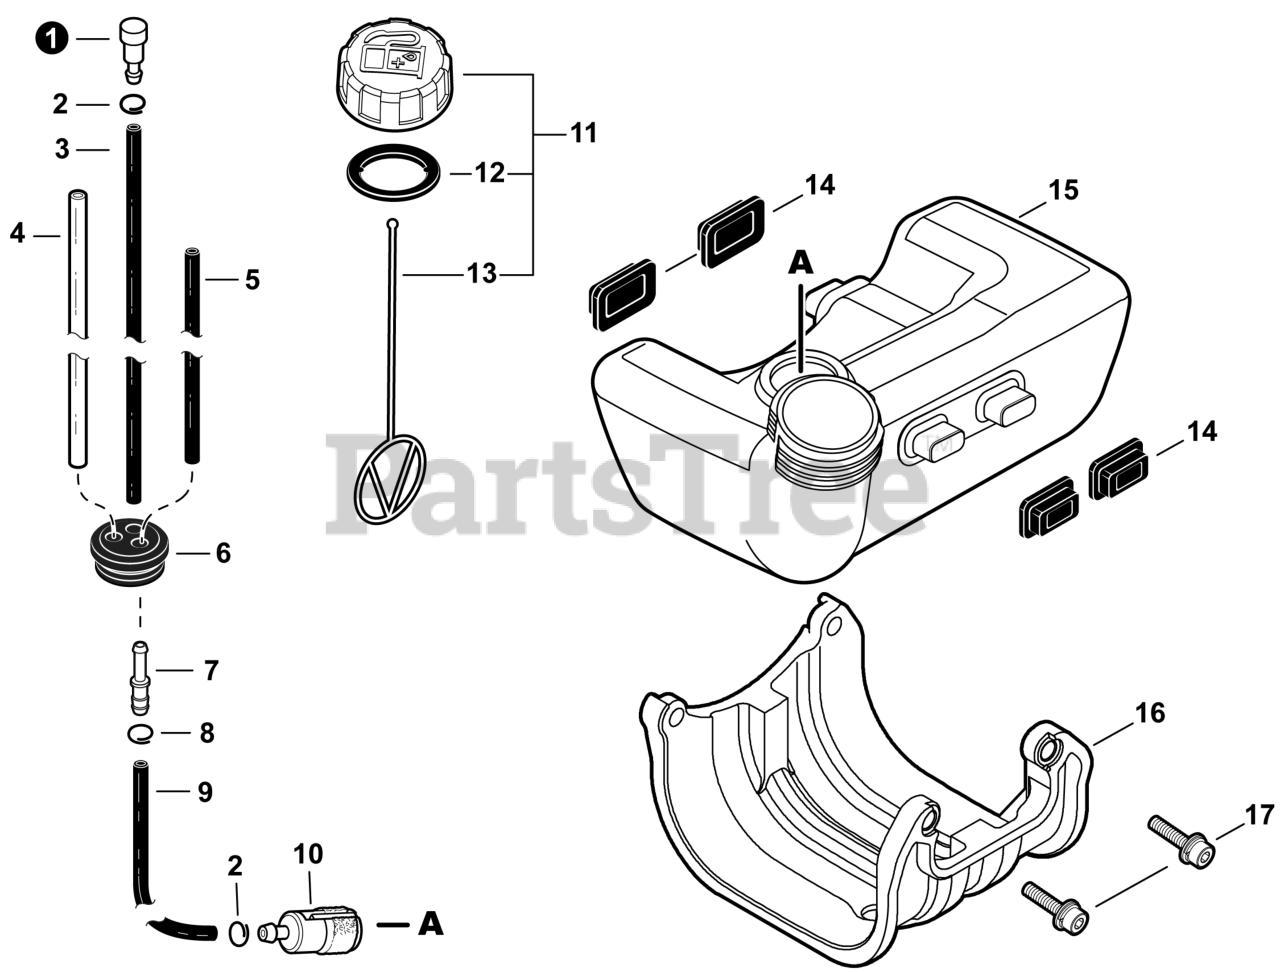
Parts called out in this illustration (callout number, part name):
1	VENT ASSY
2	CLIP Ø6
3	PIPE 3×6×80 BLACK
4	PIPE, FUEL RETURN 3×6×70
5	PIPE 3×6×50 BLACK
6	GROMMET, FUEL
7	CONNECTOR, PIPE Ø5ר3.5
8	CLIP Ø6.5 MM
9	PIPE, FUEL 3×6×120 BLACK
10	FILTER, FUEL
11	CAP ASSY, FUEL
12	GASKET, FUEL CAP
13	CONNECTOR, CAP L= 123
14	CUSHION, FUEL TANK
15	TANK, FUEL
16	GUARD, PLASTIC FUEL TANK
17	BOLT M5×20
